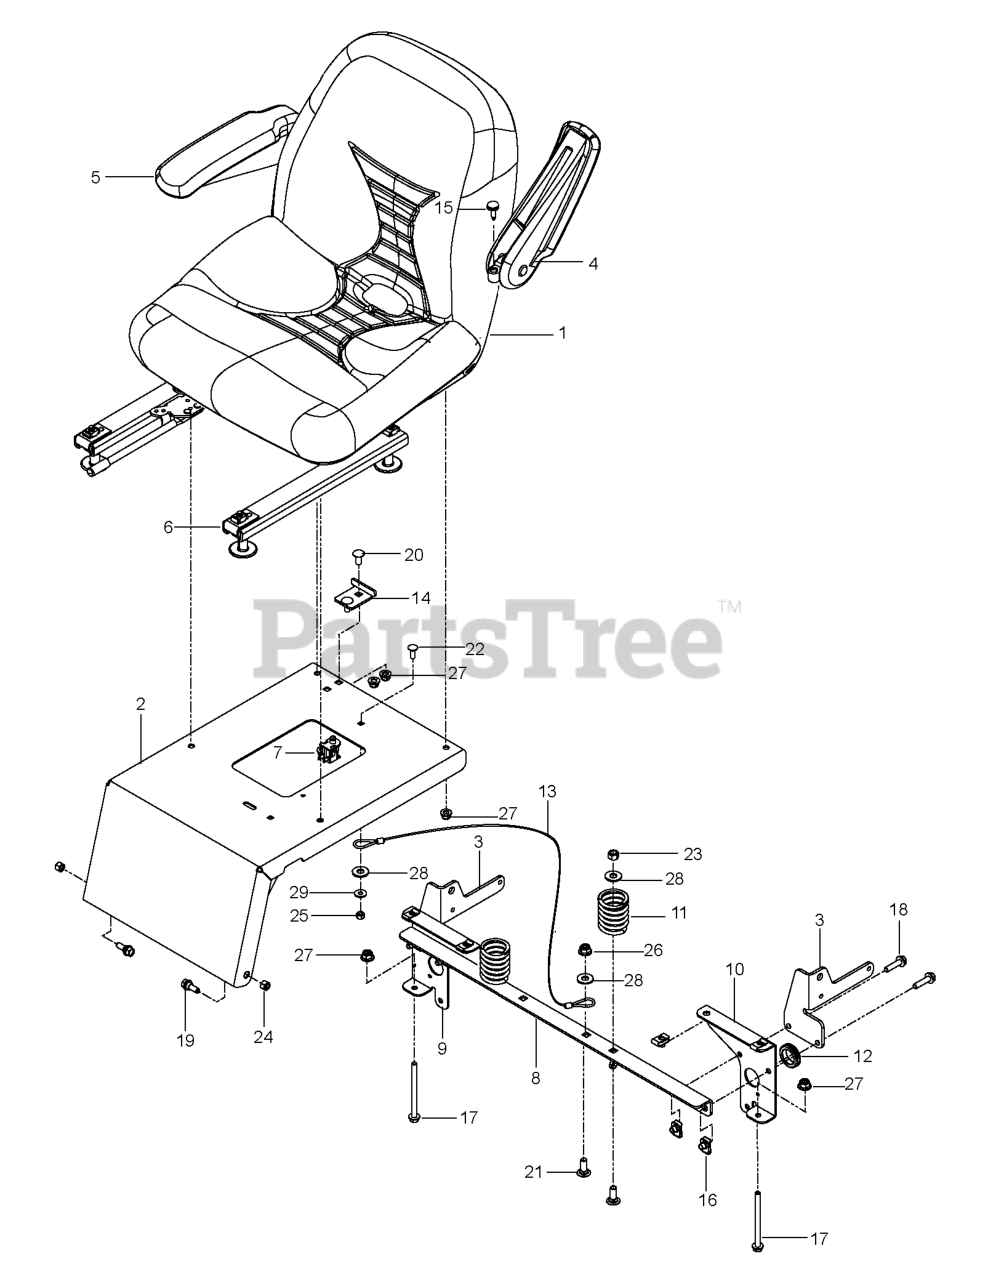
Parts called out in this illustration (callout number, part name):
1	SEAT
2	KIT.SEAT.MOUNT.W/DECAL
3	MOUNT, SEAT BELT, BLACK
4	ARMREST KIT, LT SQUARE END
5	ARMREST KIT, RT SQUARE END
6	TRACK ADJUSTMENT KIT
7	SEAT SWITCH
8	SUPPORT, SEAT
9	SUPPORT, LT, BLK
10	SUPPORT, RT, BLK
11	SPRING, SEAT
12	RUBBER GROMMET
13	SEAT LANYARD
14	STOP, SEAT - BLACK
15	ADJUSTER KNOB
16	U-CLIP 5/16-18 NUT RETAINER
17	BOLT.HEX.FLNG.5/16-18X3.75
18	HHFS 5/16-18 X 1.25 TPBLT GD 5
19	SB 5/16-18 HEX HD GD5, BLK ZN
20	RHSNB 5/16-18 X 3/4 GR5 BLK ZN
21	BOLT D
22	BOLT
23	NUT 3/8-16 NYLOC
24	NUT 5/16 NYLOC
25	NUT.1/4-20.HEX.NYLOC.ZD
26	NUT 3/8-16 HEX FLG NYLOC ZD
27	5/16-18 NYLOC FLANGE NUT
28	WASHER 3/8 FLAT
29	WASHER 1/4 FLAT
